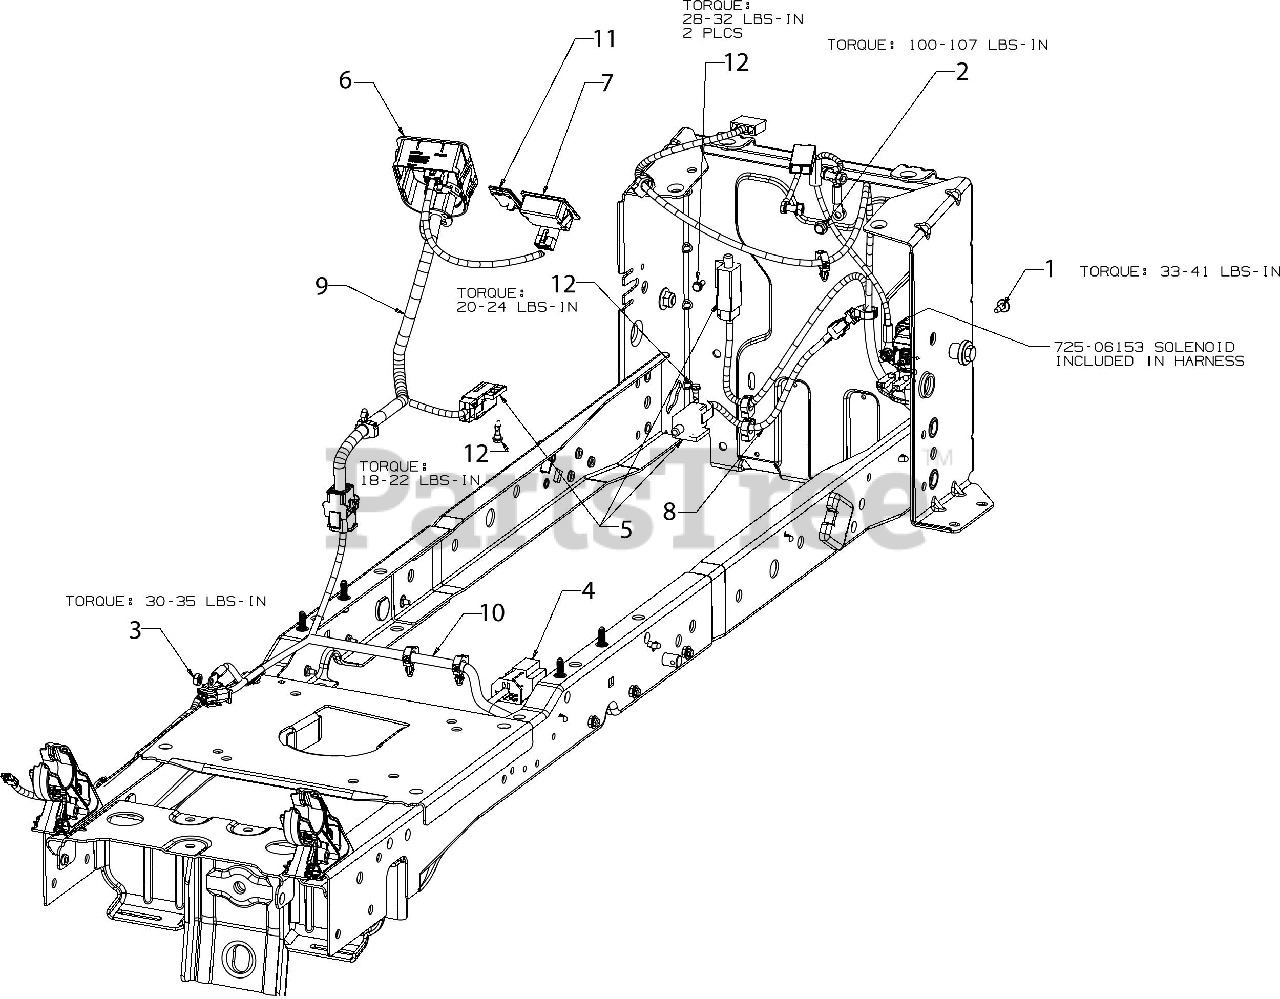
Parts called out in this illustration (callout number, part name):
1	SCREW M6-1 x .625
2	SCREW 1/4-20X.625
3	HEX NUT 1/4-20
4	3 POLE SWITCH ( NC-NO-NO)
5	INTERLOCK SWITCH (NO/NC)
6	KEY SWITCH MODULE
7	HOUR METER
8	REVERSE HARNESS
9	HARNESS
10	MAIN HARNESS M-PTO/RMC/HRMTR
11	DASH PLUG
12	SHOULDER SCREW
